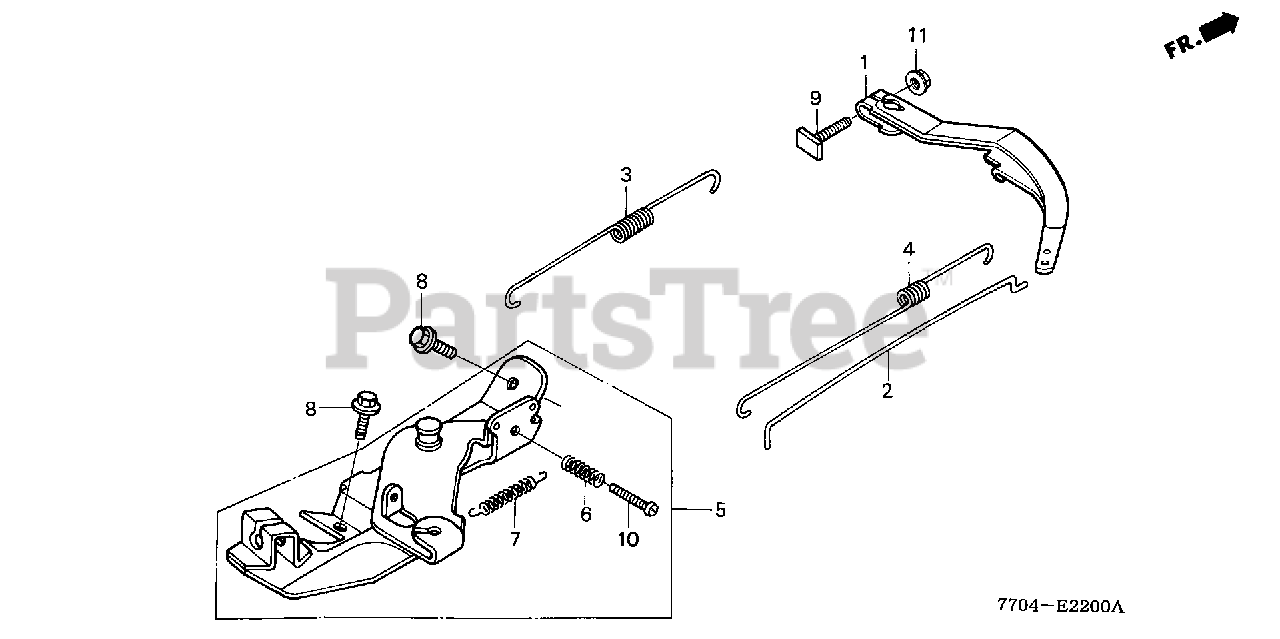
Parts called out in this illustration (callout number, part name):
1	ARM, GOVERNOR
2	ROD, GOVERNOR
3	SPRING, GOVERNOR
4	SPRING, THROTTLE RETURN
5	CONTROL ASSY.
6	SPRING, CONTROL ADJUSTING
7	SPRING, CABLE RETURN
8	BOLT, FLANGE (6X12) (CT200)
9	BOLT, GOVERNOR ARM
10	SCREW, PAN (5X28)
11	NUT, FLANGE (6MM)
